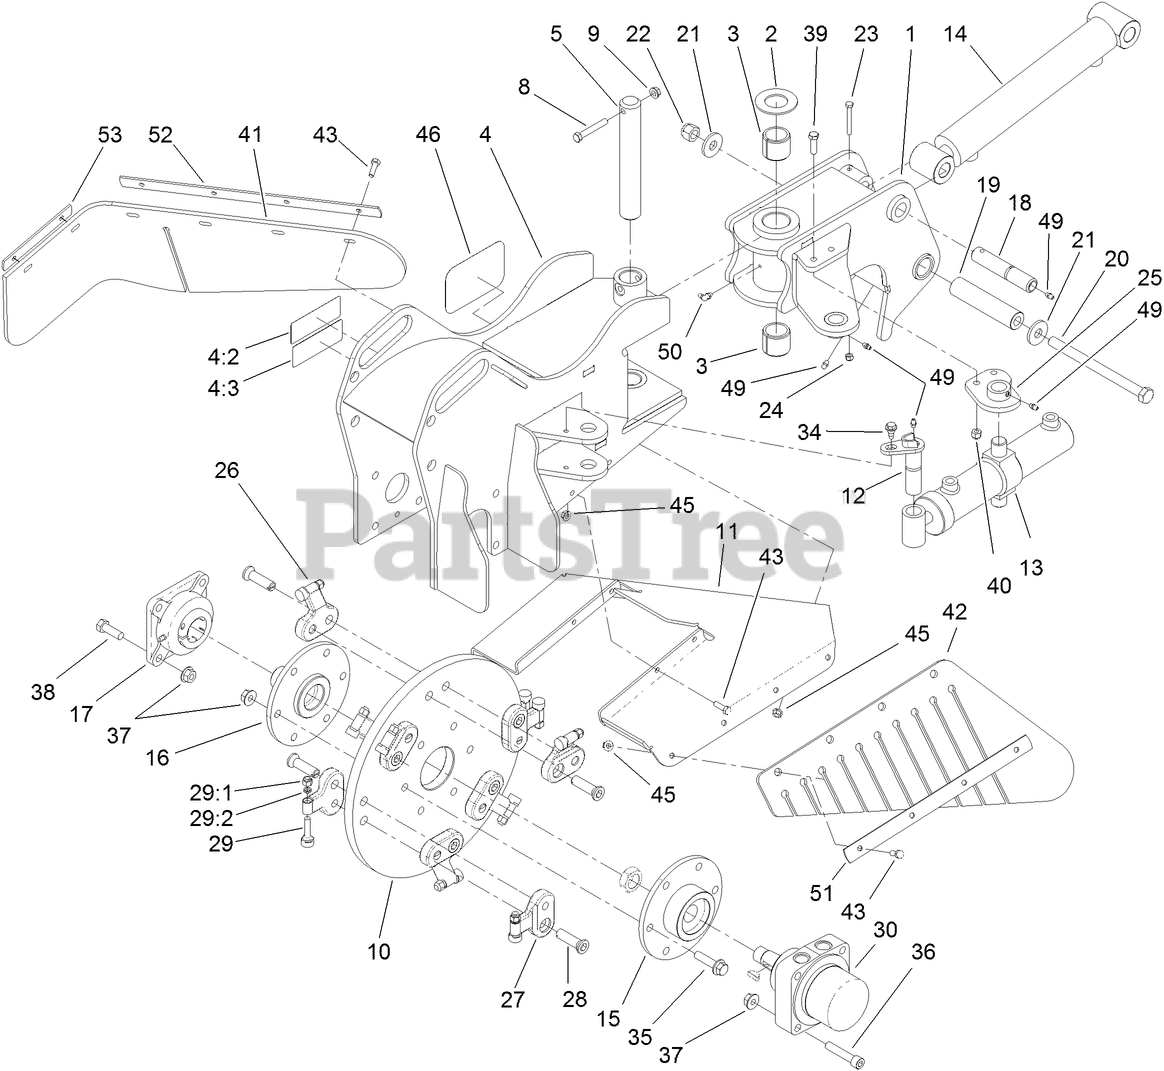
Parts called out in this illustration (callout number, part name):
2	WASHER
3	BUSHING-TENSION
4	FRAME ASM
4:2	DECAL-WARNING
4:3	DECAL-DANGER
5	PIN-PIVOT
8	SCREW-HH
9	NUT-HHF, WHIZ
10	WHEEL-CUTTER
11	GUARD-CHIP
12	PIN-PIVOT
13	HYD CYLINDER ASM
14	HYD CYLINDER ASM
15	HUB-DRIVE
16	SHAFT-STUB
17	BEARING
18	PIN-PIVOT
19	SPACER-PIVOT
20	BOLT-HH
21	WASHER-HARDENED
22	NUT-LOCK, NI
23	SCREW-HH
24	NUT-LOCK, NI
25	MOUNT-CYLINDER
26	POCKET-ANGLED
27	POCKET-STRAIGHT
28	BOLT-HSH, RH
29	GRINDER TOOTH ASM
29:1	NUT-LOCK, NI
29:2	SPACER-TOOTH
30	HYD MOTOR ASM
34	BOLT-SHOULDER
35	SCREW-HHF
36	SCREW-HSH
37	NUT-HHF
38	SCREW-HH
39	SCREW-HH
40	NUT-LOCK, NI
41	SHIELD-RUBBER, RH
42	SHIELD-RUBBER, LH
43	SCREW-HH
45	NUT-LOCK, NI
49	FITTING-GREASE
50	FITTING-GREASE, 90 DEG
51	STRAP-RETAINER, LH
52	STRAP-RETAINER, REAR
53	STRAP-RETAINER, RH
